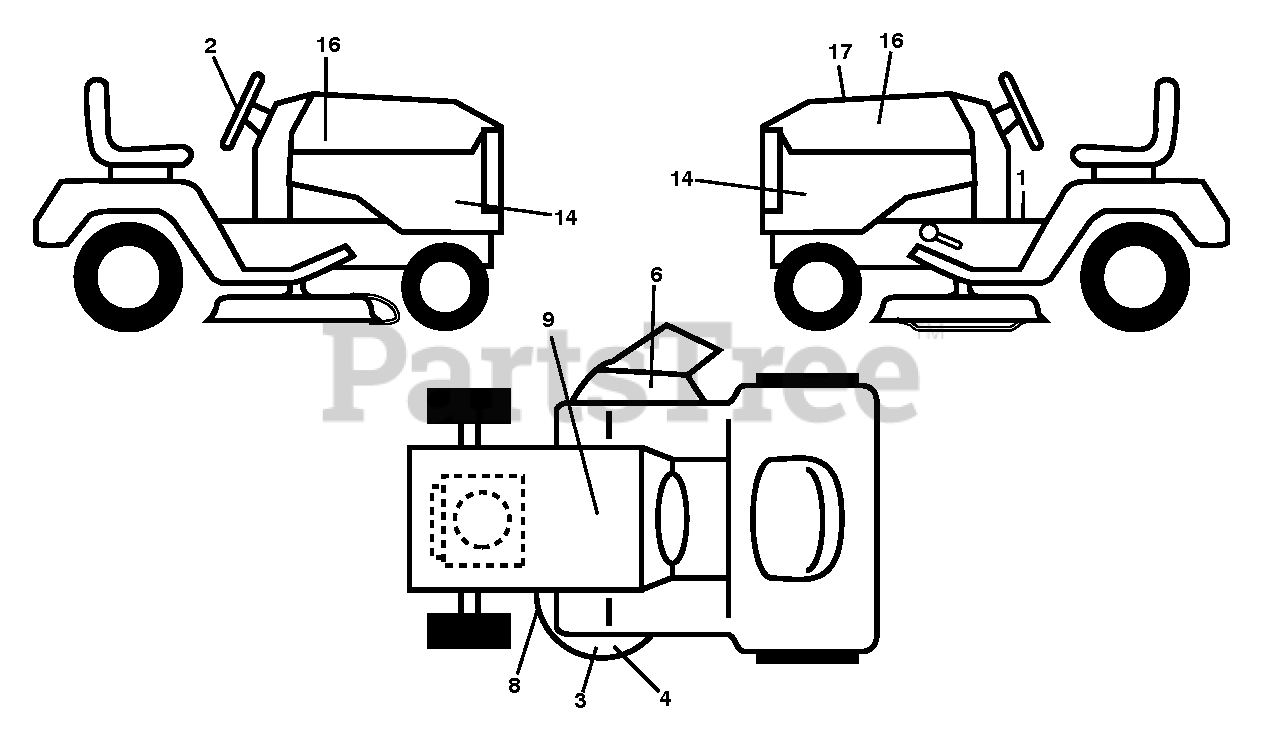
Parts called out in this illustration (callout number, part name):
1	DECAL.FENDER.WARNING.ENGLISH
2	DECAL.STRWHL.BLK.2014.PPRO
3	DECAL.MOWER.CAUTION.TENSION.AR
4	DECAL.PPRO.10YRDECKWAR.POP
6	DECAL, DECK DEFLECTOR, WARNING
8	DECAL.MOWER.SCH.48/54.PREM
9	DECAL BTRY SYMBOLS
14	DECAL.SDPNL.PBGT2654.BLK.PPRO
16	DECAL.POULAN PRO.2015
